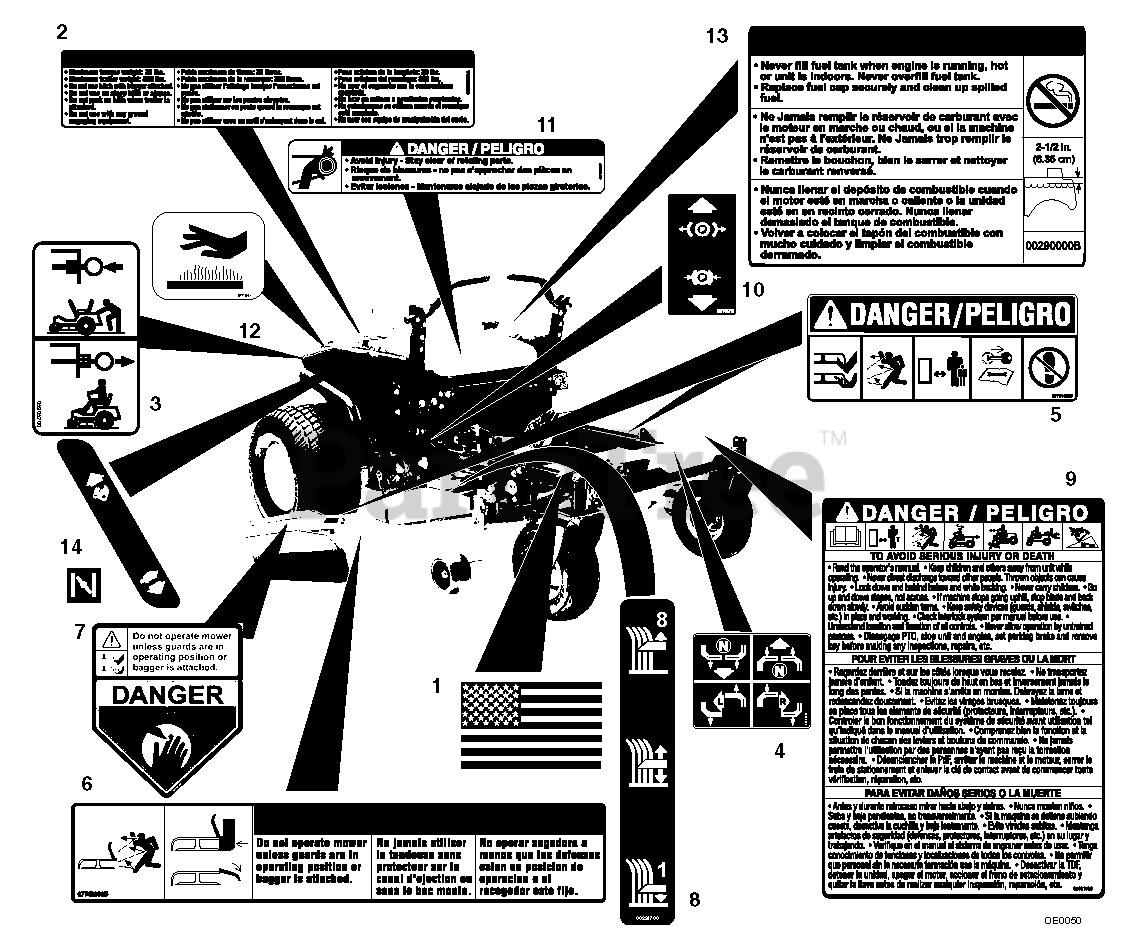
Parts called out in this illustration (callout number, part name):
1	Decal, American Flag
2	Decal, Trailer Hitch
3	Decal, Transmission Disconnect
4	Decal, Instructional Steering
5	Decal, Mower Pan Danger
6	Decal, Warning
7	Decal, CPSC Danger
8	Decal, Cut Height
9	Decal, Bilingual Danger
10	Decal, Parking Brake Lever
11	Decal, Danger
12	Decal, Hot Surface
13	Decal, Fuel Warning
14	Decal, Control
